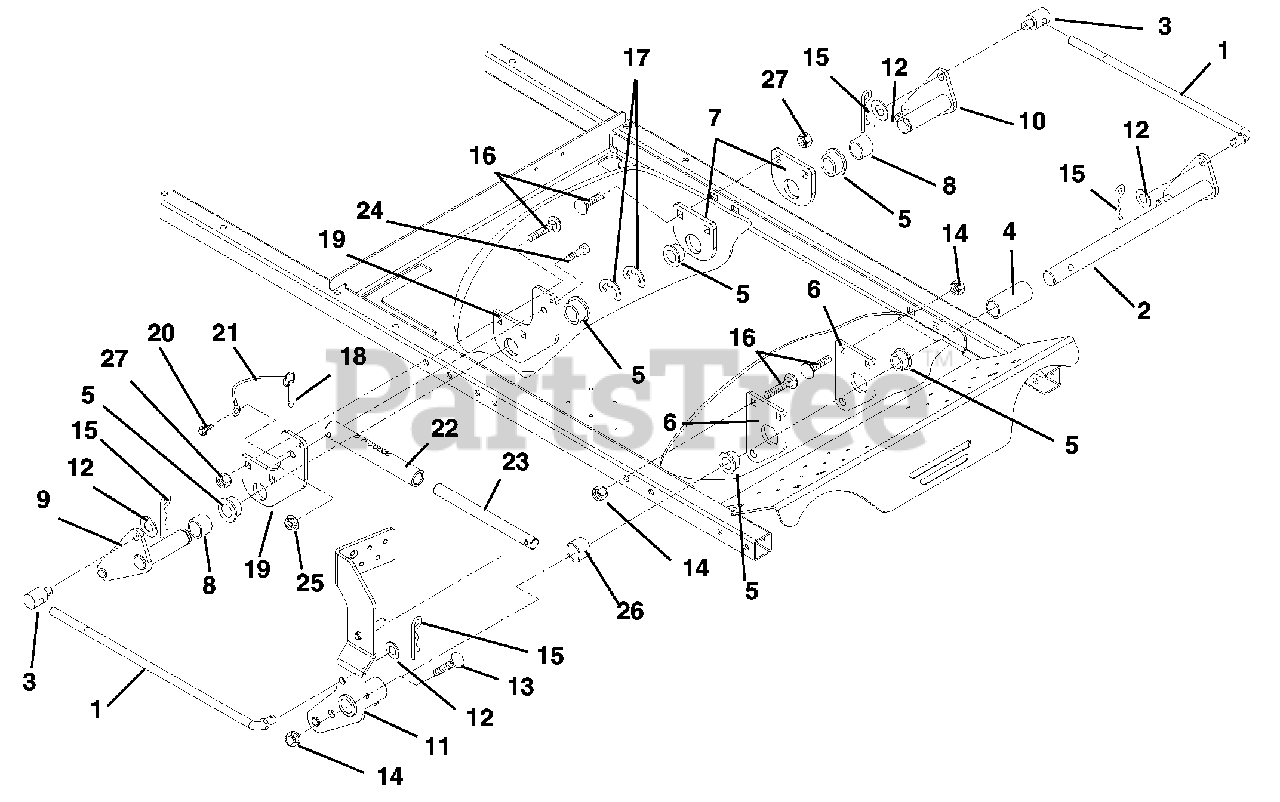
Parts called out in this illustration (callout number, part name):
1	LINKAGE, LIFT
2	WELDMENT,FRONT LIFT
3	TRUNNION-.50
4	BUSHING, FRONT
5	BSHG-FLG 1.000X1.12X.62X1.50BR
6	BRACKET, FRONT PIVOT
7	BRACKET,REAR PIVOT
8	BSHG-SPCR 1.032X1.250X.88 PM
9	WELDMENT, LIFT, REAR - RH
10	WELDMENT, LIFT, REAR - LH
11	WMT, FOOT PEDAL
12	@WSHR-FL-STL.531X1.06X.095YWZC
13	@BLT-HEX .38-16X2.00 GR5 YWZC
14	@NUT-LK-NYL-FLG .38-16 YWZC
15	PIN, HAIR, EXT - #16 YWZC
16	@BLT-RDHDSQNK .38-16X2.50 G5YZ
17	RG-RTNG .822X1.500X.050 TYP E
18	PIN, SPRING BALL .375OD X 1.50
19	MOUNT, REAR LIFT
20	@SCR-TAP .25-20X.37 HWH YWZ TR
21	LANYARD
22	TUBE, LIFT STOP
23	ROD, LIFT
24	BLT, SKH SHLD .31-18X2.25
25	@NUT-LK-NYL-FLG .31-18 YWZC
26	BSHG, SPCR 1.032X1.25X.25 PM
27	@NUT-LK-TOP-FLG .38-16 YWZC
